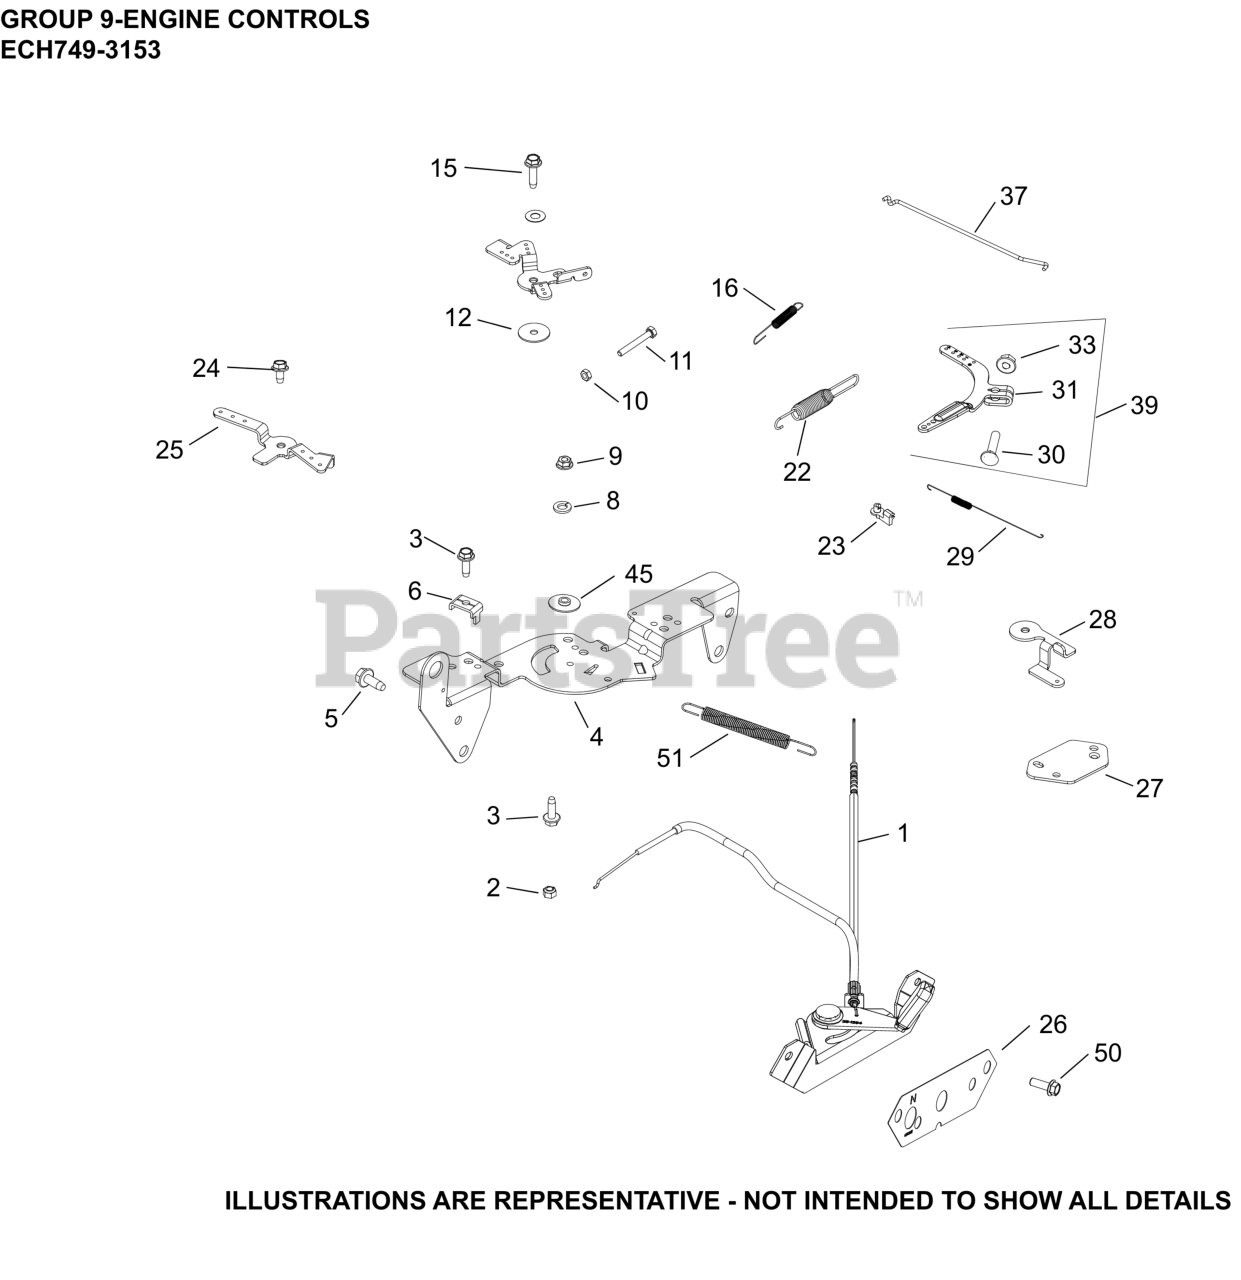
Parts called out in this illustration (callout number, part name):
1	CABLE, CONTROL ASSEMBLY
2	NUT, LOCK M5X.8
3	SCREW, THREAD FORMING
4	BRACKET, CONTROL
5	SCREW, THREAD FORMING
6	CLAMP, CABLE CABLE
8	WASHER, SPRING LOCK 1/4"
9	NUT, FLG M5X.8
10	NUT, M4X0.7
11	SCREW, CAP M4X.7X30
12	WASHER, FLAT 5.5 MM
15	SCREW, THD FRM-USE 25 086 473-S
16	SPRING, THROTTLE LIMITER
22	SPRING, GOVERNOR (ORANGE)
23	BUSHING, THROTTLE LINKAGE
24	SCREW, THREAD FORMING
25	LEVER, THROTTLE
26	LABEL, CONTROL PANEL
27	BRACKET, CABLE SUPPORT
28	LEVER, THROTTLE ACTUATOR
29	SPRING, LINKAGE
30	BOLT, RD HD SQ NECK M6X1.0X25
31	LEVER, GOVERNOR - (#2409069S)
33	NUT, FLG M6X1.0
37	LINKAGE, THROTTLE
39	LEVER, GOVERNOR ASSEMBLY
45	SPACER, CONTROL ASSEMBLY
50	SCREW, HI-LOW
51	RETURN SPRING
